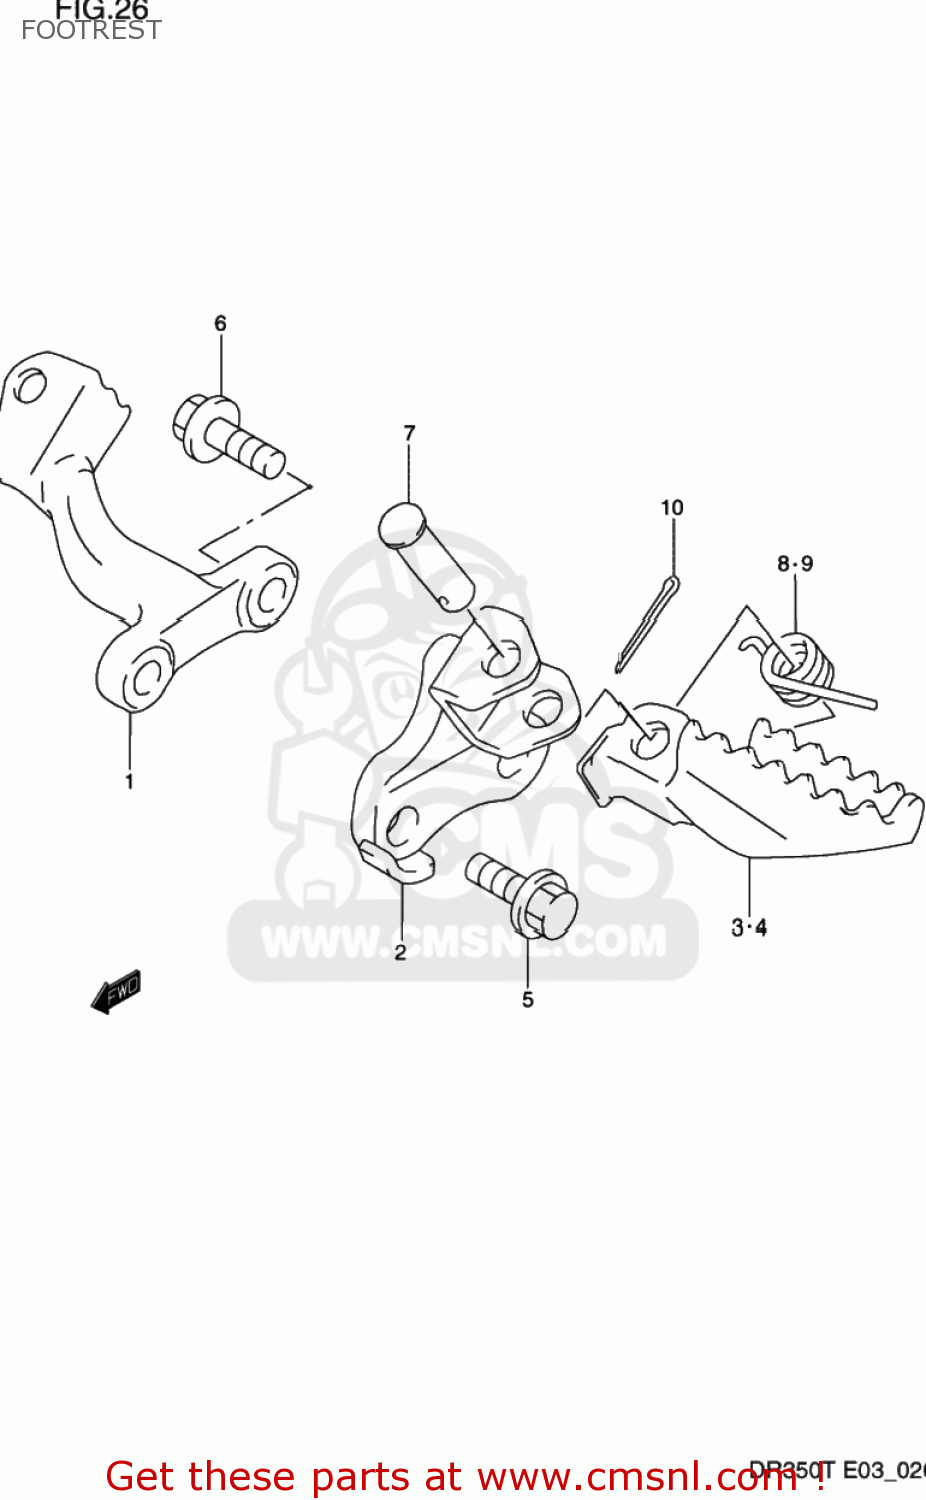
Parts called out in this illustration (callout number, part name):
1	BRACKET,FRONT FOOTREST
2	BRACKET COMP,FRONT FOOTREST
3	FOOTREST COMP,FRONT,RIGHT
4	FOOTREST COMP,FRONT,LEFT
5	BOLT
6	BOLT
7	PIN
8	SPRING
9	SPRING
10	PIN 20X20
